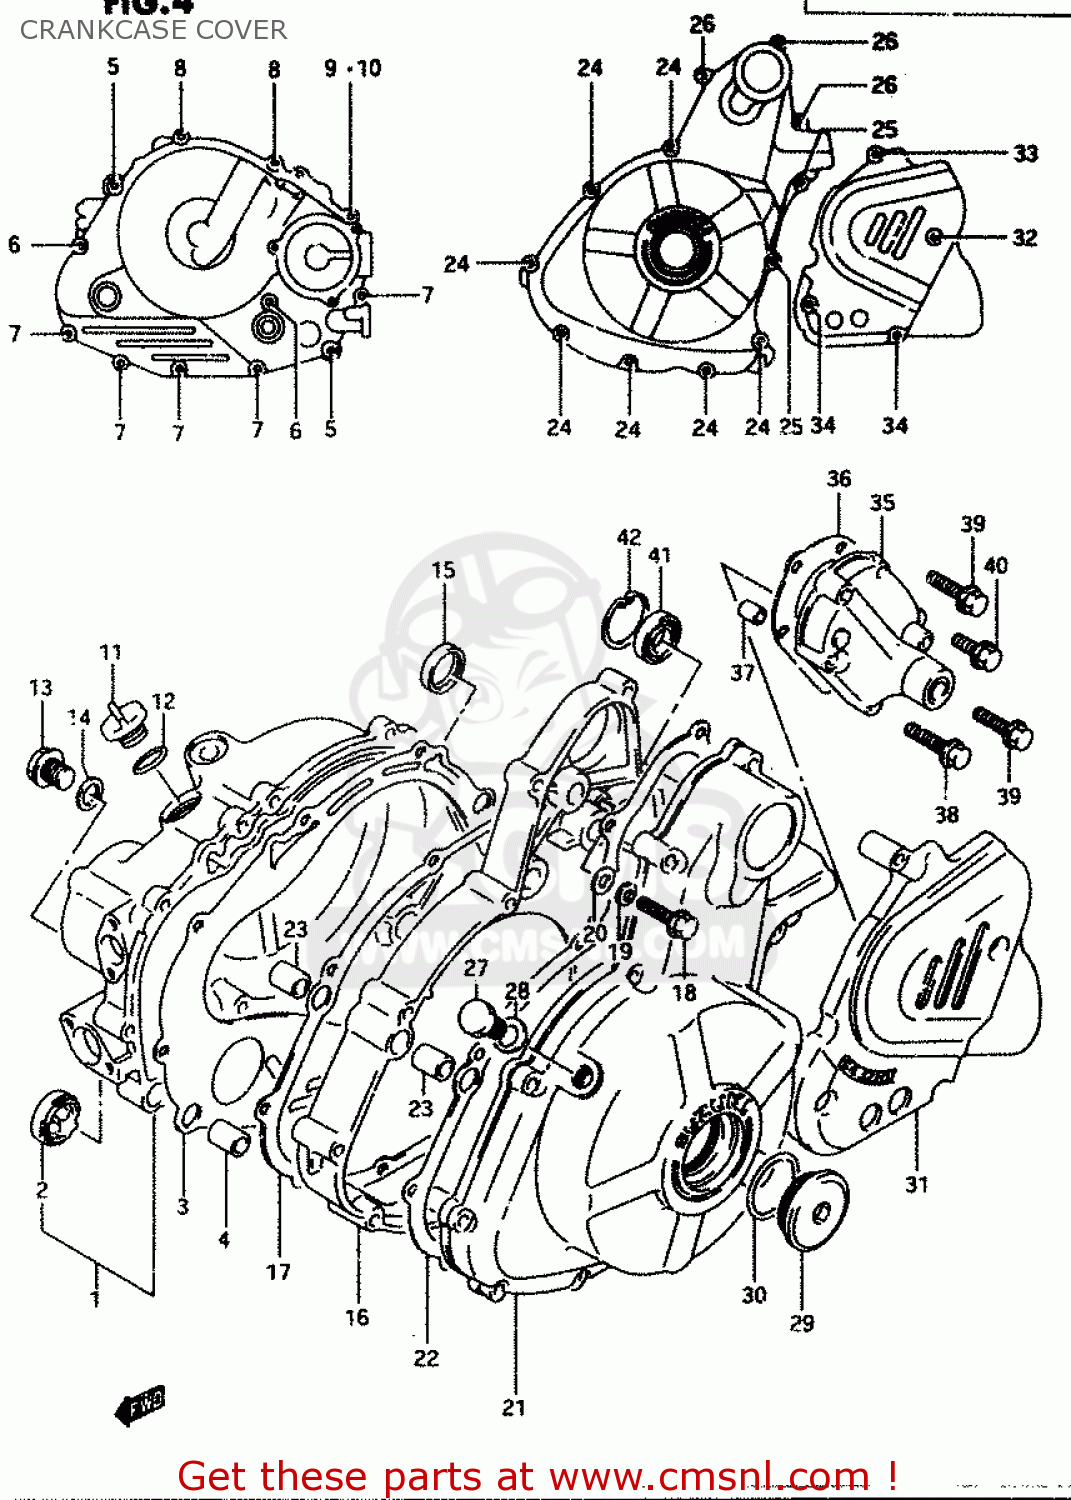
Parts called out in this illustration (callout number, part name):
1	COVER,CLUTCH
2	LENS,OIL LEVEL CHECK
3	GASKET,CLUTCH COVER (NAS)
4	PIN
5	BOLT
6	BOLT
7	BOLT
8	BOLT
9	BOLT(6X25)
10	WASHER
11	PLUG
12	O RING(D:3.1,ID:16.8)
13	PLUG(14X12)
14	GASKET(13.8X18.8X4.8) (NAS)
15	PLUG,CLUTCH COVER KICK
16	COVER,GENERATOR,INNER
17	GASKET,MAGNETO COVER (NAS)
18	BOLT,G/S SWITC
19	LOCK WASHER
20	WASHER
21	COVER,GENERATOR OUTER
22	GASKET,GENERATOR OUTER COVER (NAS)
23	PIN
24	BOLT
25	BOLT
26	BOLT
27	PLUG(12X9)
28	GASKET(12.1X16.2X3.7) (NAS)
29	PLUG(SILVER)
30	O RING(D:3.1,ID:32.7)
31	COVER,ENGINE SPROCKET
32	BOLT
33	BOLT
34	BOLT
35	COVER,GEAR SHIFT
36	GASKET,GEAR SHIFT COVER (NAS)
37	PIN
38	BOLT
39	BOLT,G/S SWITC
40	SCREW
41	BEARING(12X28X8)
42	CIRCLIP
